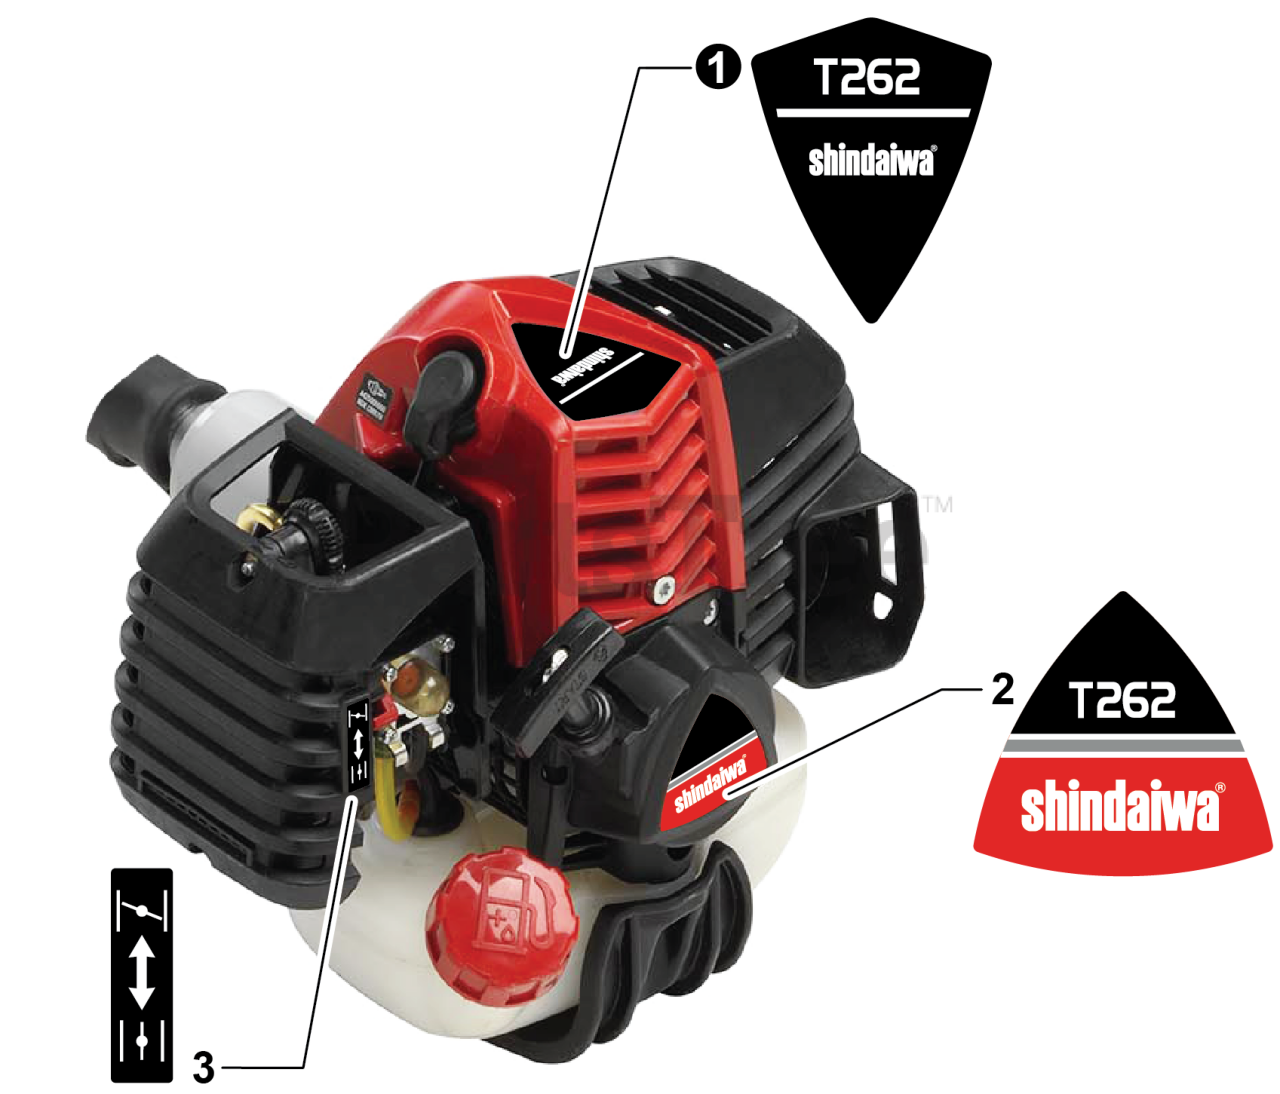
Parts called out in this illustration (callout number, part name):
1	LABEL - MODEL T262
2	LABEL - RECOIL STARTER
3	LABEL - CHOKE
